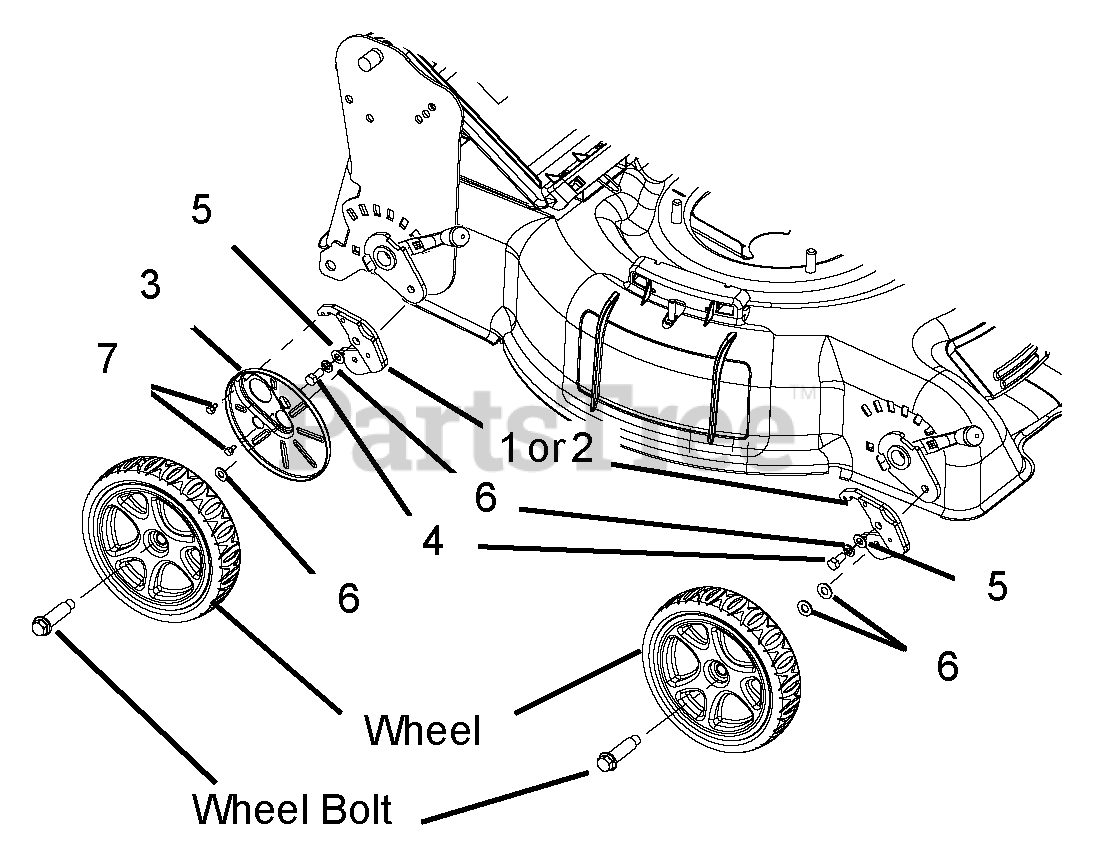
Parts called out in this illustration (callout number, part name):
1	External Left Hand Bracket
2	External Right Hand Bracket
3	Wheel Cover
4	3/8" x 3/4" Hex Bolt
5	3/8" Lock Washer
6	13/32" Flat Washer
7	3/8" Tapping Screw
